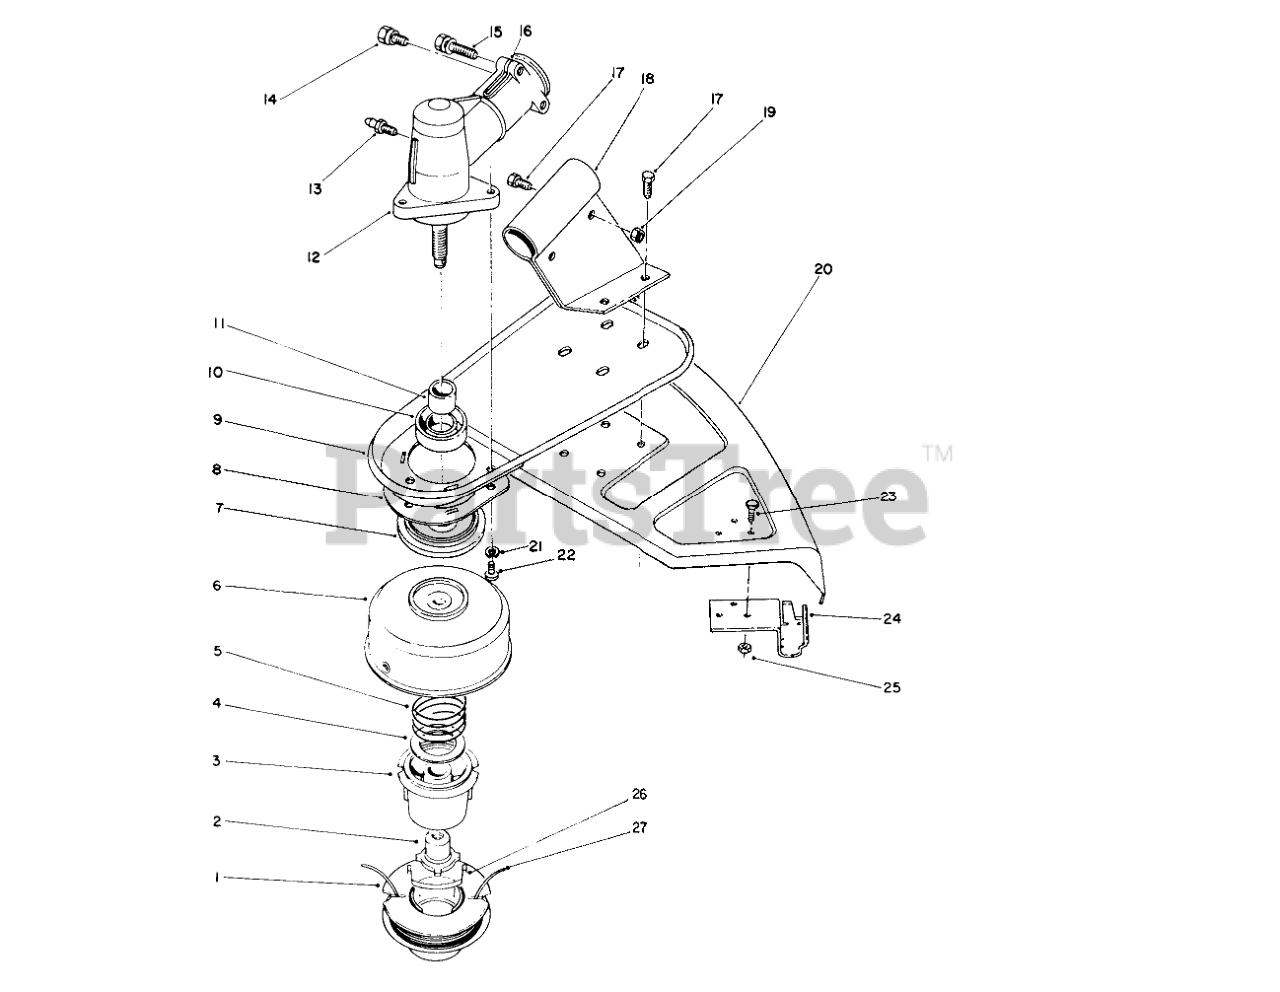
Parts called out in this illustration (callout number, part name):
1	Spool-Prewound (Incl. Ref. #26)
2	LH DRIVER
3	SPOOL CORE
4	WASHER-FLAT
5	SPRING
6	ASM - TRIMMER DRUM & EYELET
7	DUST CAP F/W
8	GRASS WRAP GUARD
9	SHIELD SUPPORT R
10	OIL SEAL
11	SPLINED SLEEVE
12	Gear Box Assembly (Incl. Ref. #10, 11, & 13-16)
14	HHMS SCREW
15	HHMS SCREW
16	WASHER
17	SCREW-SHH
18	SHIELD BRKT
19	NUT-LOCK, NI
20	Shield-Grass
21	LOCKWASHER
22	SCREW
23	SCREW-SHH
24	Brace & Knife Blade Ass-y (Incl. Ref. #23-25)
25	NUT-LOCK, NI
26	SADDLE-SPOOL CAP
27	REPL LINE PKG
